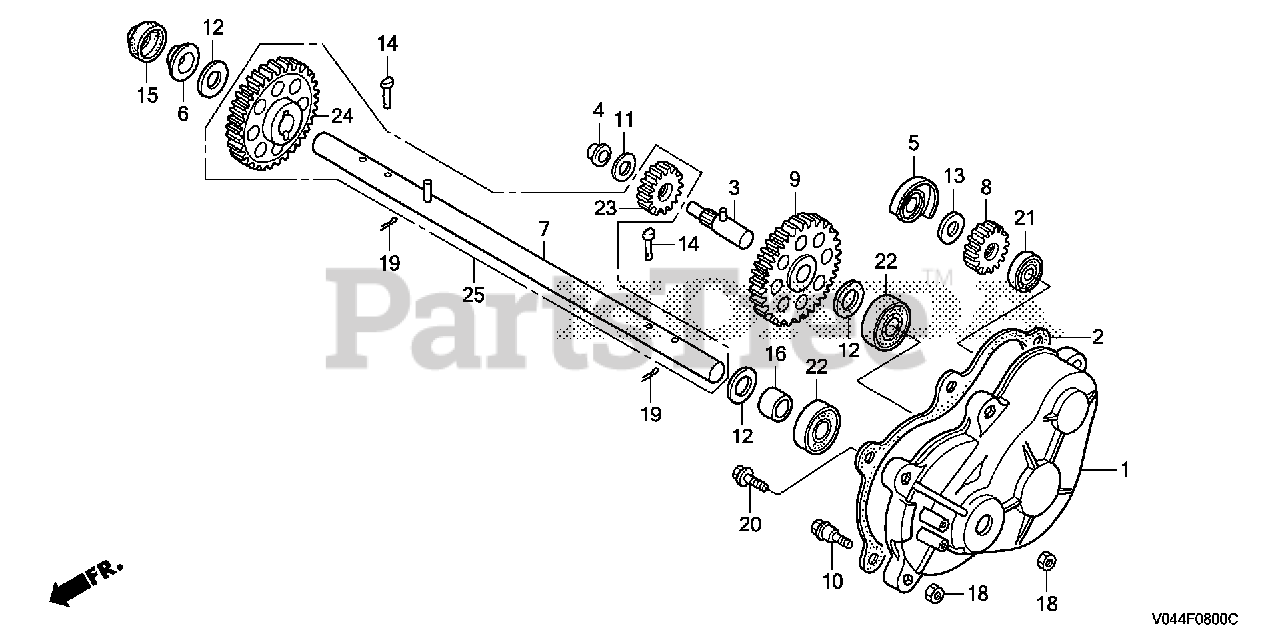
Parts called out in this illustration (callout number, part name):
1	CASE, R. TRANSMISSION
2	GASKET, TRANSMISSION CASE
3	COUNTERSHAFT
4	BUSH, COUNTERSHAFT
5	BUSH, CROSS SHAFT
6	BUSH, FINAL SHAFT
7	SHAFT, WHEEL
8	GEAR, DRIVE (19T)
9	GEAR, DRIVEN (48T)
10	BOLT, TRANSMISSION SETTING
11	WASHER, THRUST (12MM)
12	WASHER, DIFFERENTIAL GEAR
13	WASHER, THRUST (15X24X2)
15	DUST SEAL (20X34X7.5)
16	COLLAR, WHEEL SHAFT
18	NUT, HEX. (6MM)
19	PIN, SPLIT (3.0X25)
19	PIN, COTTER (3.0X45)
20	BOLT, FLANGE (6X18)
21	BEARING, RADIAL BALL (6002UU)
22	BEARING, RADIAL BALL (6004UU)
23	GEAR, FINAL DRIVE (15T)
24	GEAR, FINAL DRIVEN (38T)
